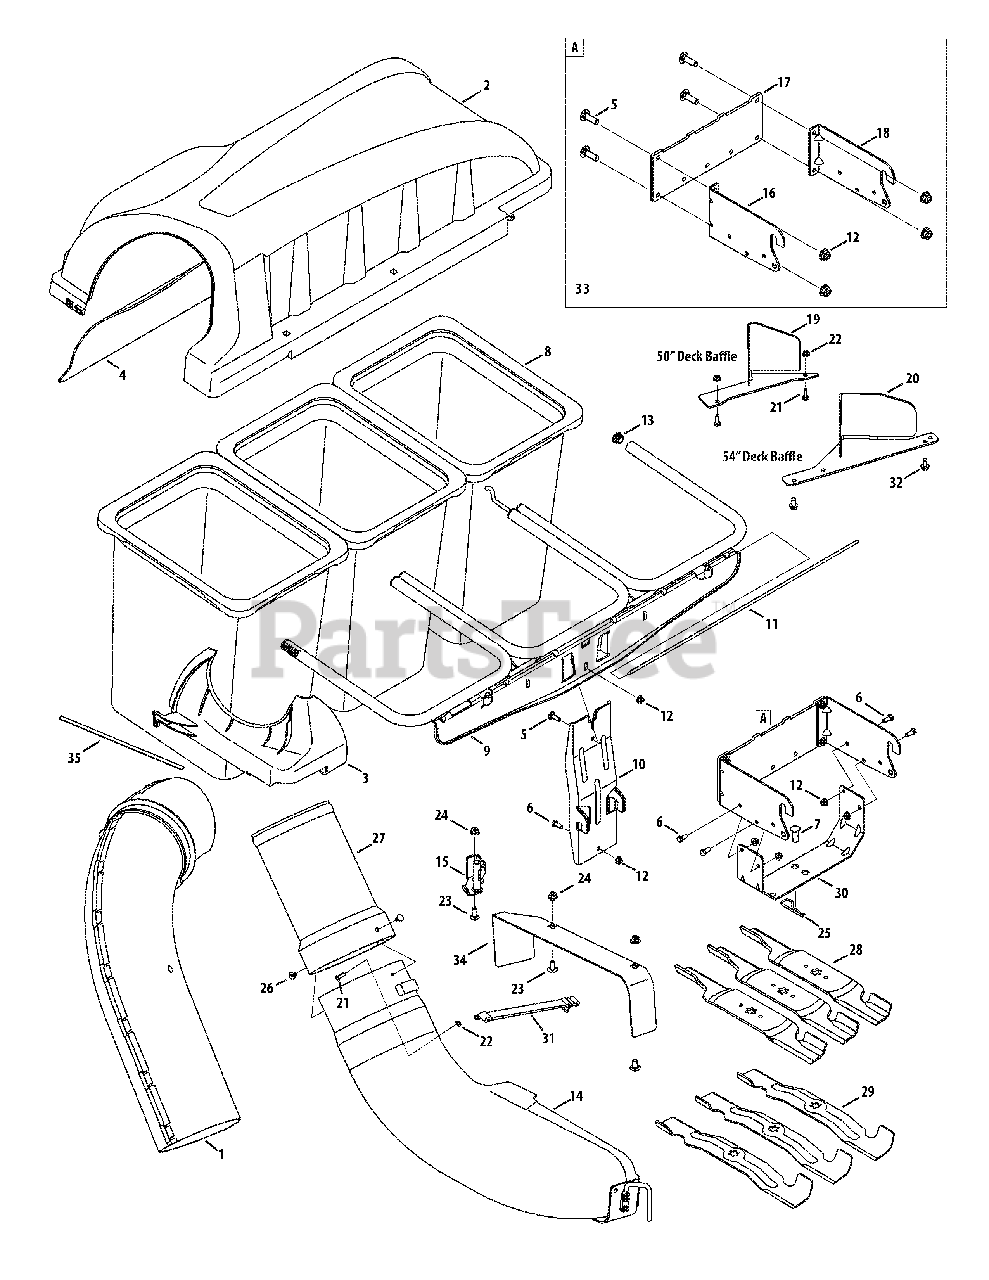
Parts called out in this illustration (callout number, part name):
1	Upper Chute Assembly
2	Triple Bagger Cover Assembly
3	Upper Chute Support
4	Bagger Cover Screen
5	Carriage Screw, 5/16-18 x 1.00"
6	Hex Head Screw, 5/16-18 x .75"
7	Clevis Pin, .62" Dia.
8	Grass-bag Assembly
11	Cover Hinge Pin
12	Flange Lock Nut, 5/16-18
14	Discharge Chute Elbow, 50/54" Deck
15	Chute Stop-Bracket
16	Hitch Bracket, RH
17	Universal Rear Attachment Bracket
18	Hitch Bracket, LH
19	Deck Baffle, 50"
20	Deck Baffle, 54"
21	Tap Screw, 1/4 -20 x .750 (50" Deck)
22	Flange Lock Nut, 1/4 -20 (50" Deck)
23	Carriage Screw, 3/8 -16 x 1.00"
24	Flange Lock Nut, 3/8 -16
25	Internal Cotter Pin, .148 x 3.00
26	Ratchet Clip, .250
27	Bagger Chute Adapter, 7 In.
28	Blade, 17.90 Lg., Star Bagging
29	Blade, 18.50 Lg., High Lift
30	Universal Bracket Support
31	Chute Strap
32	Tap Screw, 5/16-18 x .750 (54" Deck)
33	Mounting Bracket Kit (Incl. Ref. 16-18)
34	Discharge Chute Plate
35	Adesive Foam Strip
